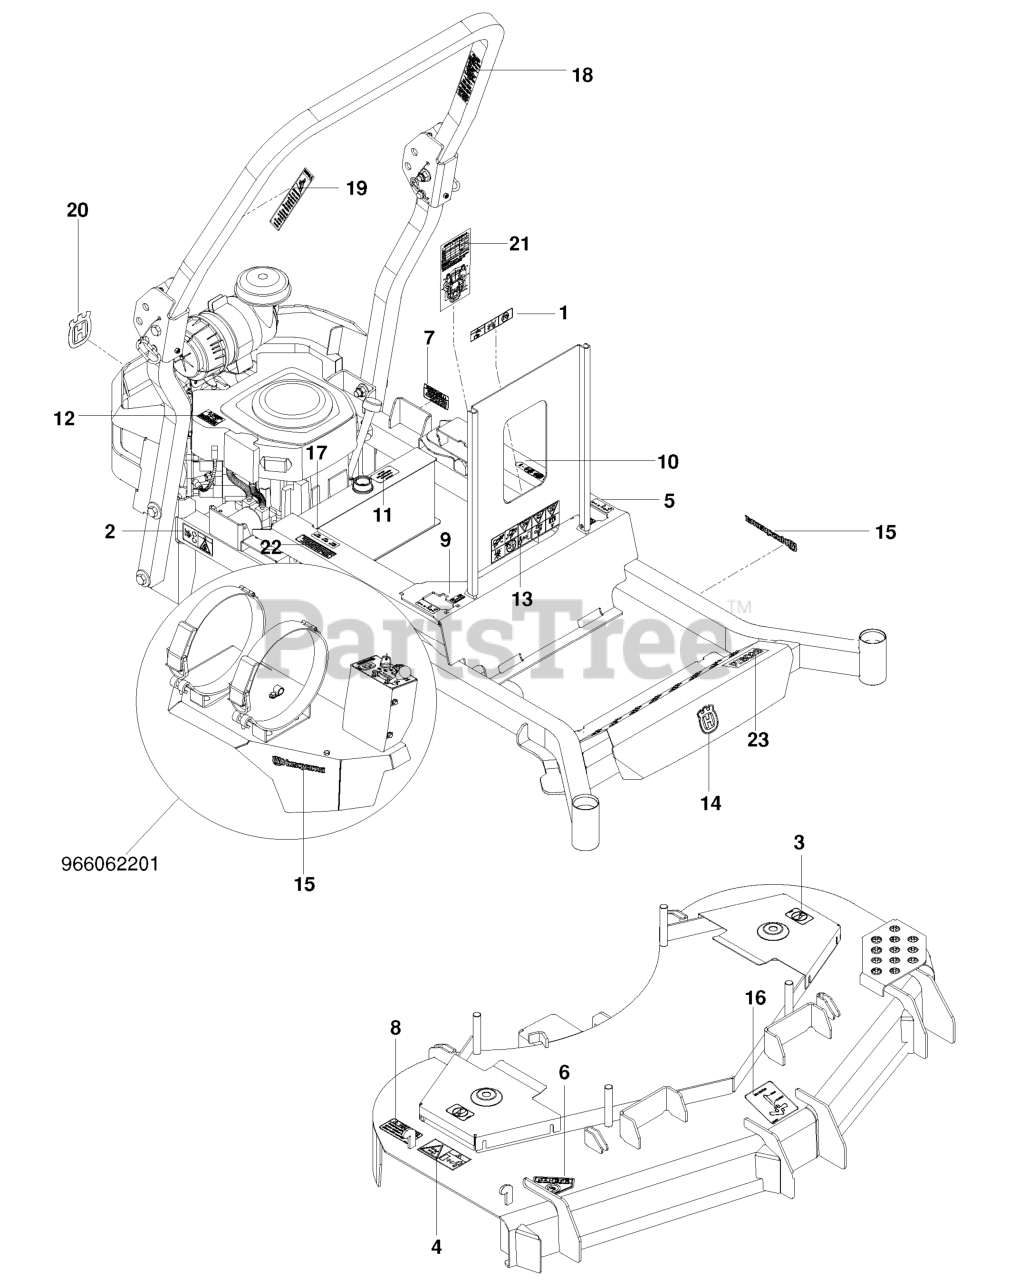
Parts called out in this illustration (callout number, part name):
1	EURO DECAL-BATTERY WARNIN6
2	DECAL, BELT DRIVE
3	DECAL, NO STEP
4	DECAL, EURO SEVERING
5	DECAL, MOTION CONTROL
6	DECAL, CPSC
7	DECAL, PROP. 65
8	DECAL, CAUTION
9	DECAL, F.S.T.
10	DECAL, PARK BRAKE
11	DECAL, OIL TANK
12	DECAL, EXHAUST
13	DECAL, WARNING
14	DECAL, CROWN H 70MM
15	DECAL.HOOD.LOGO.ORANGE.HUSQVAR
16	DECAL, BELT ROUTING
17	DECAL, FUSE
18	DECAL, ROPS
19	DECAL, ROPS, WARNING
20	DECAL, CROWN H, 110MM
21	DECAL, SERVICE
22	DECAL, WARNING SPARK ARRESTOR
23	DECAL, PZ5426
